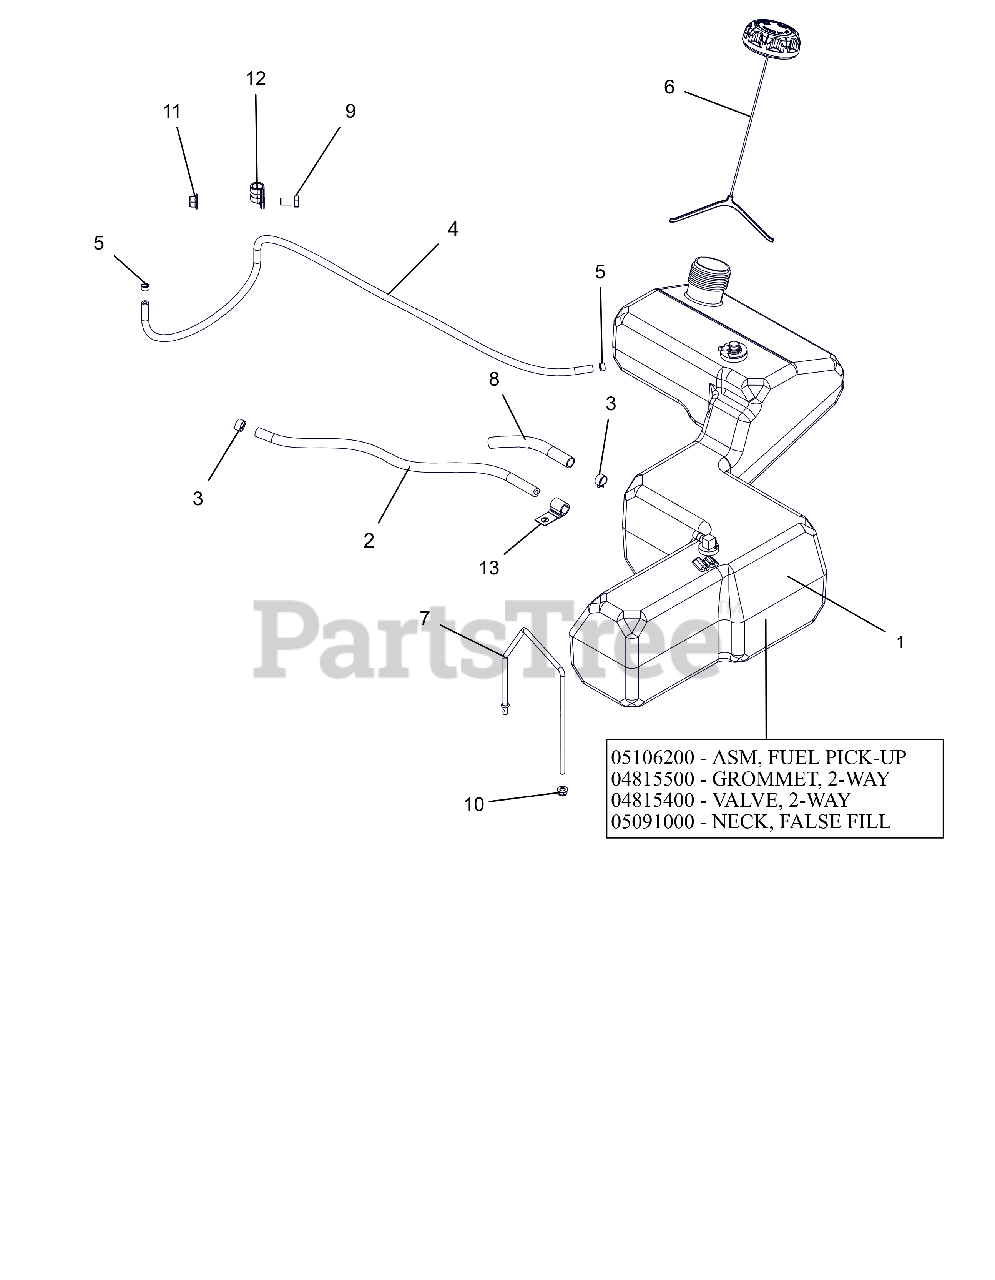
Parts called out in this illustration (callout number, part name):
1	ASSEMBLY, FUEL TANK IKON(2017)
1	ASM, IKON FUEL PICK-UP
1	GROMMET, 2-WAY
1	VALVE, 2-WAY
1	NECK, FALSE FILL-2017 IKON
2	HOSE, .25 LOW-PERM BULK GAS
3	CLAMP, FUEL LINE
4	HOSE, .188 LOW-PERM BULK GAS
5	CLAMP-HOSE, SPRING .188
6	CAP, FUEL VENT-IN 2.25" RATCH.
7	BRKT, FUEL TANK HOLD DOWN
8	WRAP, ANTIABRASION .5X.064WALL
9	@BLT-HEX .38-16X.75 GR5 YWZC
10	@NUT-LK-NYL-FLG .25-20 YWZC
11	@NUT-LK-NYL-FLG .38-16 YWZC
12	CLAMP, CUSHIONED STEEL
13	J-CLAMP
